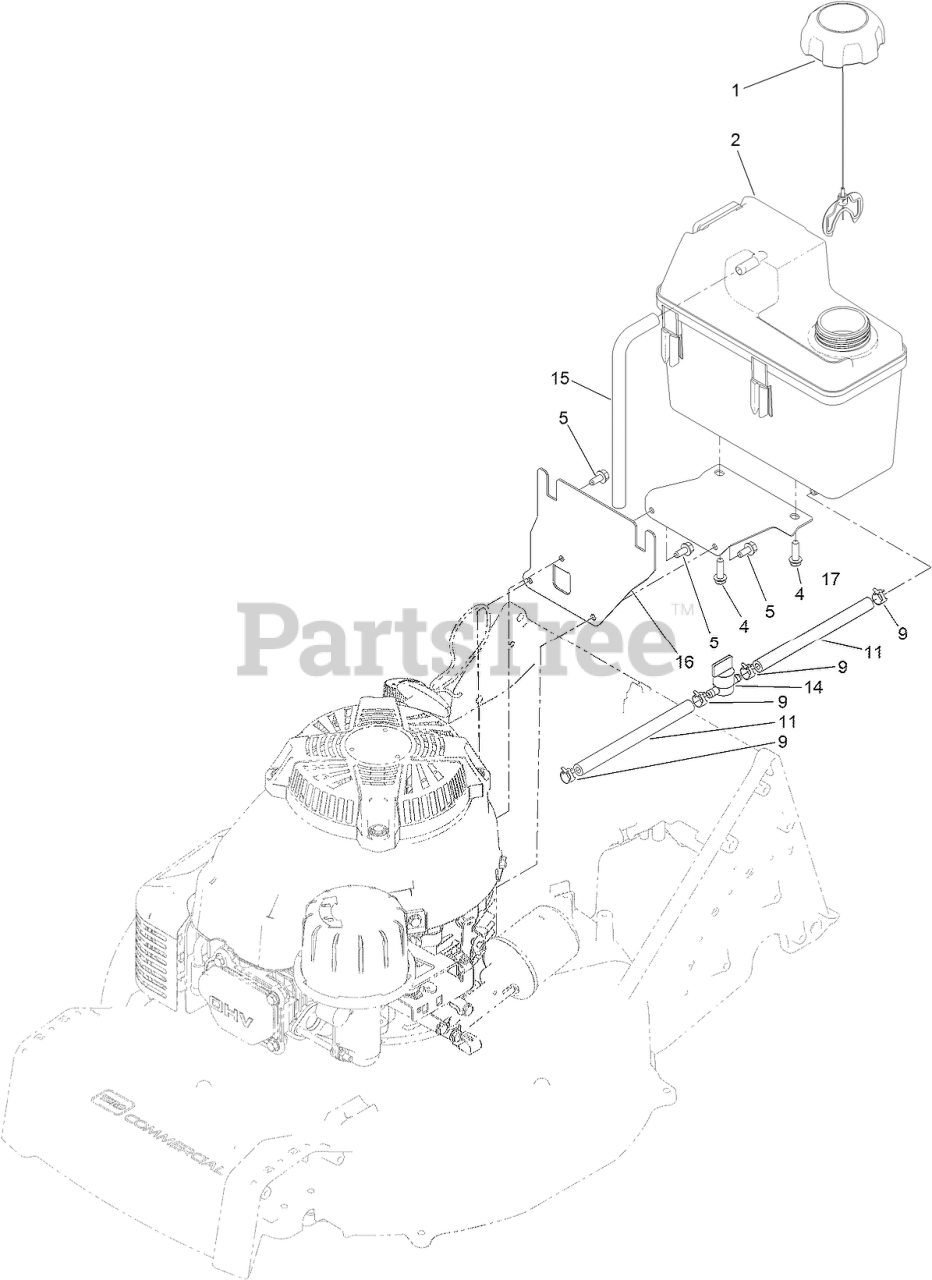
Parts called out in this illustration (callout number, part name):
1	CAP-RATCHET, TETHERED
2	TANK-FUEL
4	SCREW-HWH
5	SCREW-HWH
9	CLAMP-HOSE
11	HOSE-FUEL
14	VALVE-FUEL
15	HOSE-VENT, CANISTER
16	BRACKET-TANK, MOUNTING
17	BRACKET-TANK, SUPPORT
